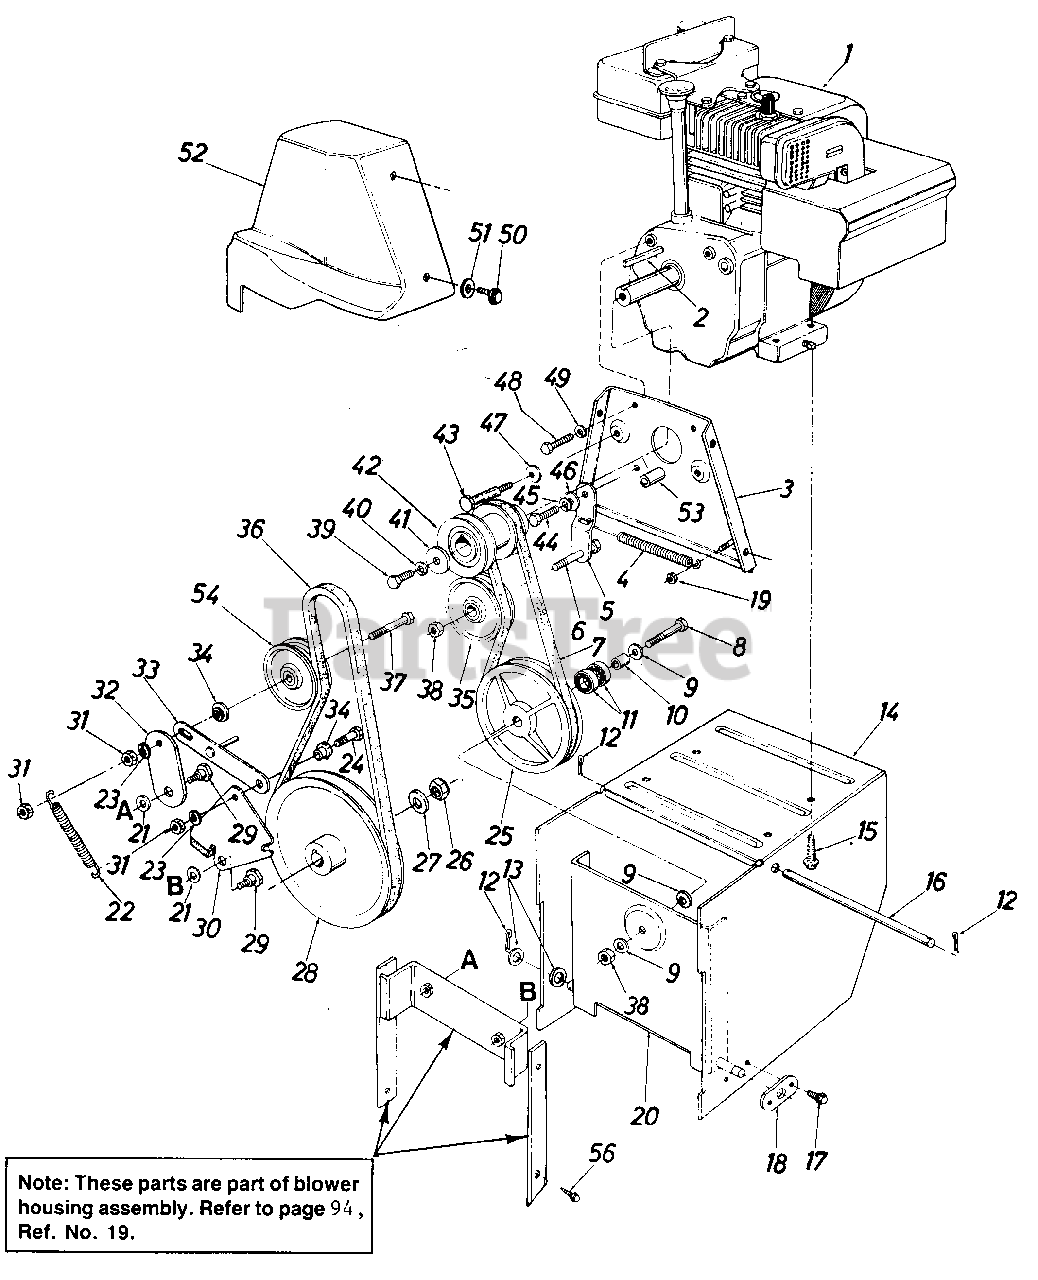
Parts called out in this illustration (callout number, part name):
2	KEY-SQ 3/16X1.50
3	PLATE ASSY-ENG
4	SPRING-EXTENSION
5	BRACKET-IDLER
6	SCREW 3/8-24X1.25 GR5
7	BELT-V 3/8 X 29
8	SCREW-HEX 3/8-24 X 1.50 GR.5
9	WASHER-BELL .400 ID X .88 X .060
11	BEARING-BALL
12	PIN-COTTER-3/32 DIA X .75
13	WASHER-FL .510 X .995 X .060
14	FRAME ASSY
15	SCREW-HEX SLF TAP 3/8 X 1 3/8
17	SCREW-HEX WASH SF TAPP
18	XXX
18	BRACKET-AXLE
19	NUT-HEX CENTER L-1/4-20
20	BRACKET ASSY-PULLEY SUP
21	WASHER-BELL .3/8ID X 1.12OD X .030
22	SPRING-EXTENSION
23	WASHER-LOCK-3/8
24	SCREW-HEX-3/8-16 X 1.250
25	PULLEY-DRIVE
26	NUT-HEX CENTER L-5/8-18
27	WASHER-FL-.635 ID X .93 OD X .060
29	SCREW-SHLD .625 DIA X .163
30	BRACKET-BRAKE
31	NUT-HEX JAM 3/8-18
32	BRACKET-IDLER
33	LINK ASSY-BRAKE
34	SPACER-SHLD
35	PULLEY-IDLER-FLAT-2 1/4 OD X 3/4
36	BELT-V 3/8 X 38 SL
37	SCREW-HEX 3/8-16 X 2.250
38	NUT-HEX INS L-3/8-24
39	SCREW-HEX 3/8-24 X 1.50 GR.5
40	WASHER-LOCK-3/8
41	WASHER-FL-HOND .410ID X 1.255X.162
42	PULLEY
43	SCREW-SHLD .498 DIA X 3.00
44	SCREW-HEX SPECIAL 5/16-24X1.0
45	WASHER-LOCK-5/16
46	SPACER-SHLD
47	WASHER-BELL .400 ID X .88 X .060
48	SCREW-HEX 5/16-24 X .62
49	WASHER-LOCK-5/16
50	SCREW-HEX WASH SF TAPP
51	WASHER-FL-.28 ID X .74 OD X .063
52	COVER-BELT
53	SPACER
54	PULLEY-IDLER-FLAT W/FLANGES
56	SCREW-HEX WASH SF TAPP 3/8 X 3/4
